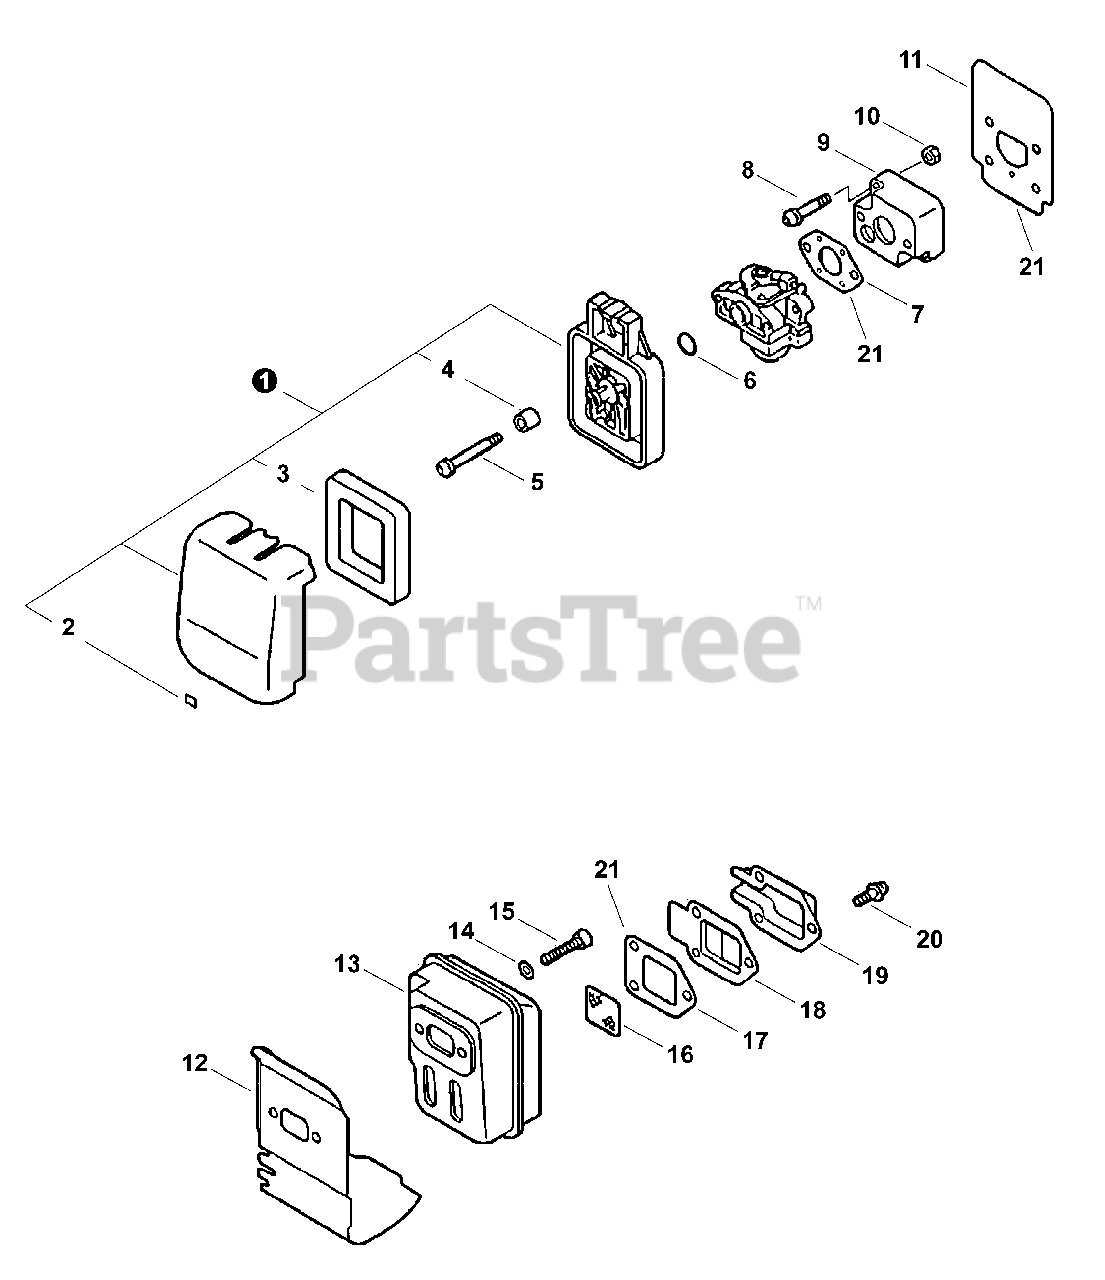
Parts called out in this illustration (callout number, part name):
1	AIR CLEANER ASSY
3	FILTER, AIR
4	SLEEVE
5	SCREW - 5×64
6	O-RING - 15
7	GASKET, INTAKE
8	SCREW - 5×22
9	INSULATOR, INTAKE
11	SHIELD, INTAKE
12	GASKET, EXHAUST
13	MUFFLER
14	WASHER - 5
15	SCREW - 5×55
16	SCREEN, SPARK ARRESTOR
17	GASKET, EXHAUST
18	GASKET, EXHAUST - INNER
19	GUIDE, EXHAUST - OUTER
20	SCREW - 4×10
21	GASKET KIT
